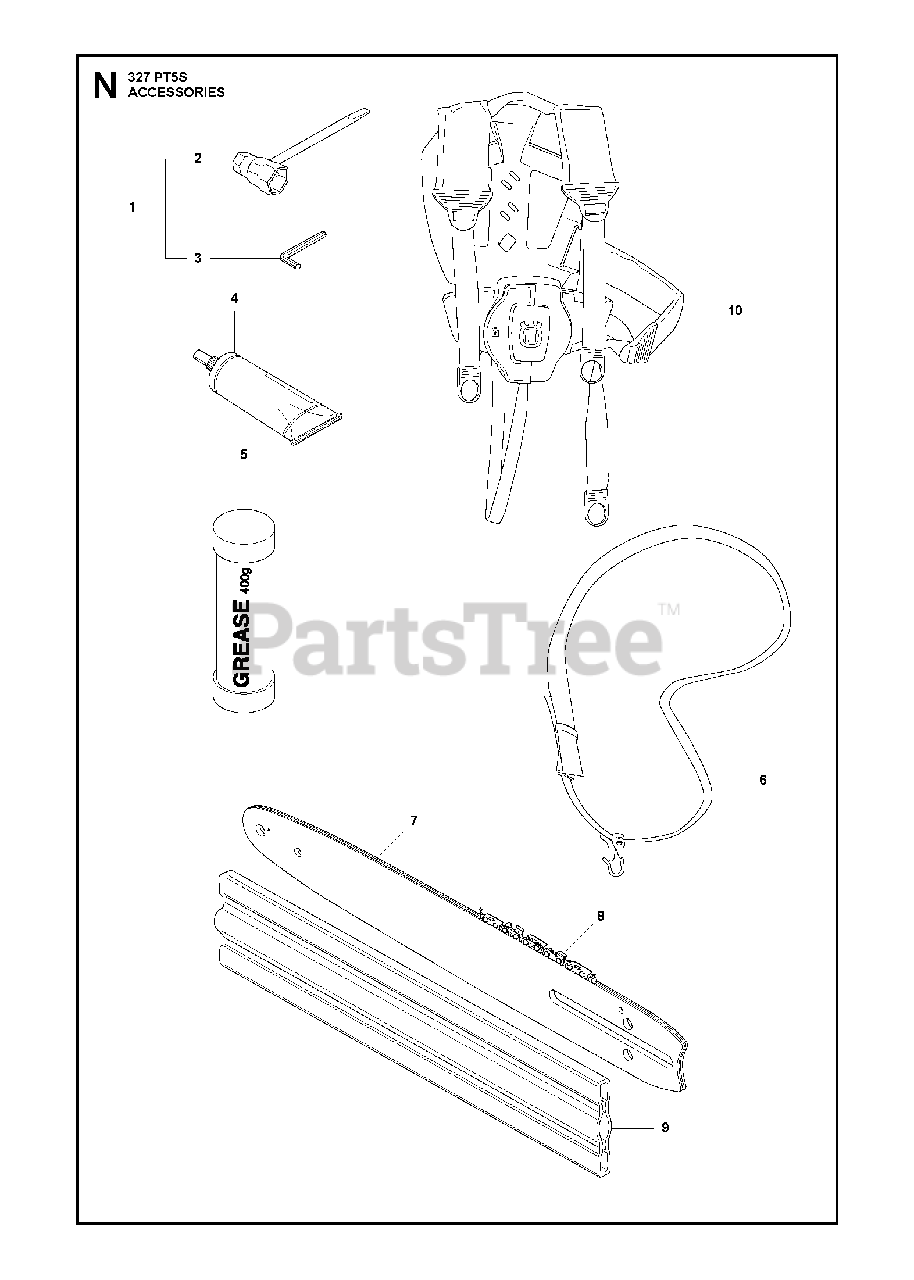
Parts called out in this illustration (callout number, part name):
1	ACCESSORY KIT
2	COMBI TOOL
3	L-KEY WRENCH
4	Gear Grease, Tube
5	GREASE 400 GRAMS
6	Shoulder Strap with Sign
6	STRAP
7	BAR 1/4" A318 10" 58DL
7	Guide Bar, 12" 1/4 .050 A318
8	Saw Chain, 1/4" 1.33mm H00 Loop
8	Saw Chain, 12" H00-64 1/4" 1.3mm R25AP064X Loop
10	BALANCE FLEX HARNESS
